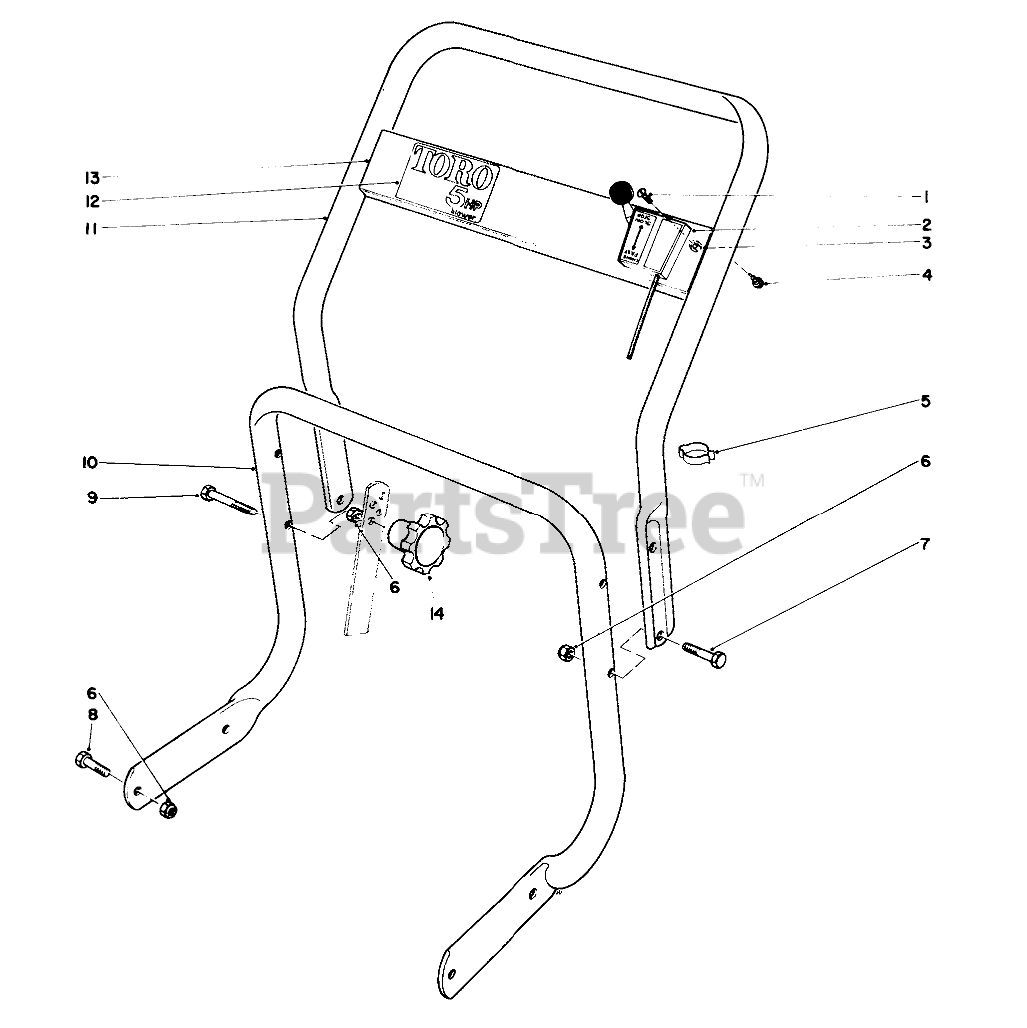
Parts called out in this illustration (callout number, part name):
1	8-32 X 1/2 RND HD MS
2	Throttle Control
3	NUT-HEX
4	SCREW-HWHTF
5	BODEN CLIP
6	NUT-LOCK, NI
7	SCREW-HH
8	SCREW-HH
9	SCREW-HH
10	HANDLE
11	Handle
12	ESCUT PLATE DECAL
13	BLOWER ESCUTCHEON PLT
